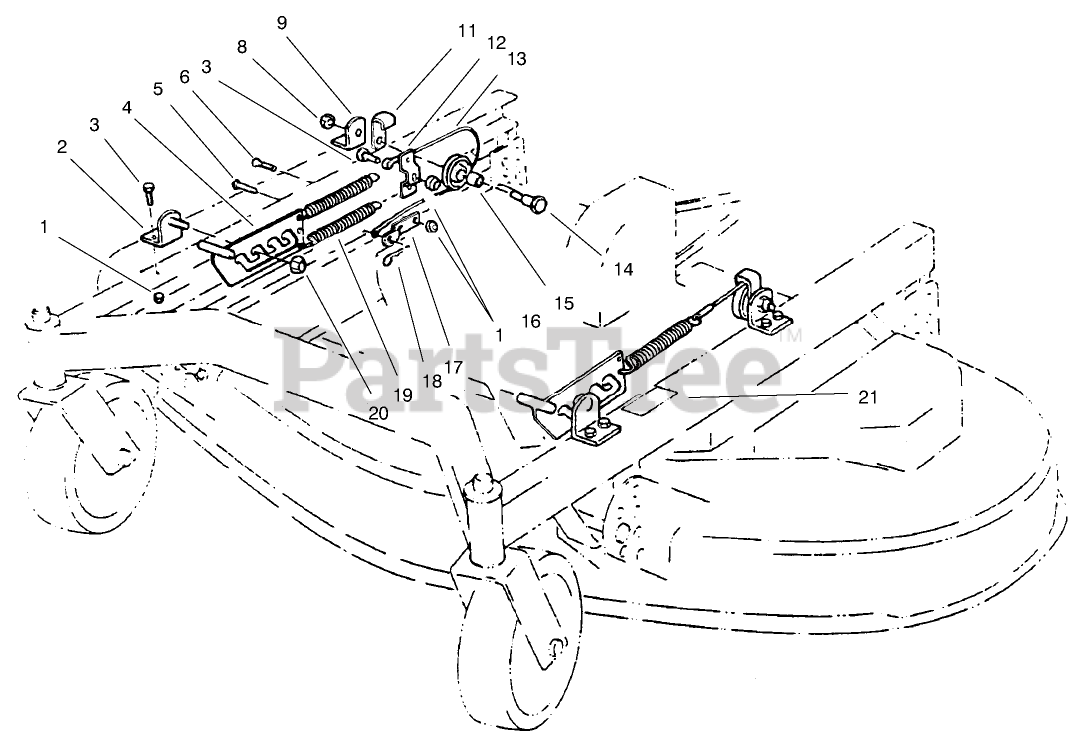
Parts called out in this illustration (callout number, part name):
1	NUT-LOCK, NI
2	Bracket-Control
3	SCREW-HH
4	Control-Tension
6	1/4-20 X 5/8 RD HD SC
8	NUT-LOCK, NI
9	Bracket-Pulley
11	CABLE RETAINER
12	SPRING BRACKET
13	CABLE
14	BOLT-SHOULDER
15	Bushing
16	Pulley Assembly (Incl. Ref. #15)
17	Bracket-Anchor
18	PIN-COTTER
19	EXTENSION SPRING
20	NUT-HF
21	DECAL-WARNING
